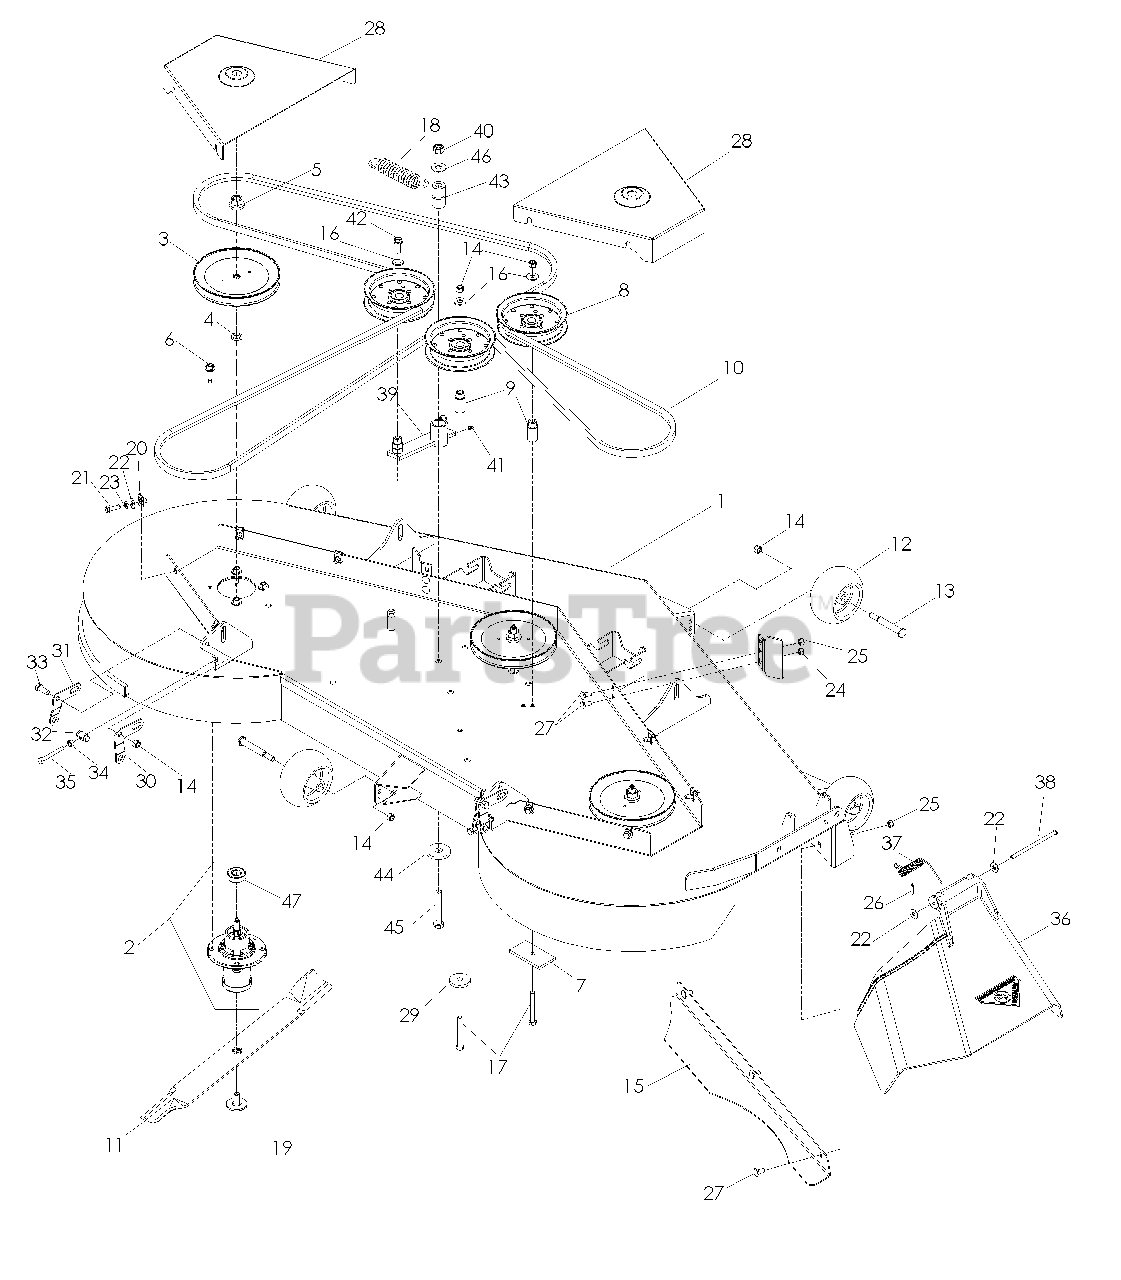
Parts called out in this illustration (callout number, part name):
1	DECK, W/DECALS
2	HOUSING ASSEMBLY
4	WASHER-SPACER
5	NUT 9/16 TOP CENTER LOCK
6	SCREW, WASHER HEAD
7	PAD, PAINTED
8	PULLEY, IDLER
9	IDLER BUSHING
10	BELT, DECK
11	BLADE, 25"
12	WHEEL, GAUGE
13	BOLT, SHOULDER
14	NUT 3/8-16 HEX NYLOC
15	CONFINEMENT PLATE, 72"
16	WASHER, 3/8 FLAT STD
17	HCS 3/8-16 x 3
19	BOLT, 7/16, BLADE
20	RETAINER, U TYPE
21	HCS 5/16-18 x 1
22	WASHER, 5/16 STD FLT
23	WASHER 5/16 SLW
25	NUT 5/16-18 HEX NYLOC
26	PIN, COTTER 1/8 x 3/4
27	RHSNB 5/16-18 x 3/4
28	SHIELD, BELT-72"
29	HEAVY WASHER
30	PITCH, ADJUST, RT
31	PITCH, ADJUST, LT
32	TRUNION, PITCH
33	HCS 3/8-16 x 1
34	NUT 5/16-18 HEX
35	HCS 5/16-18 x 2 1/2 TPBLT
36	DISCHARGE CHUTE-72"
37	SPRING-TORSION
38	PIN, CLEVIS 5/16
39	IDLER ARM WELDMT
40	NUT 1/2 HEX NYLOC
41	ZERK
42	HCS 3/8-16 x 1 WHIZLK
43	PIVOT BUSHING
44	SUPPORT WASHER
45	HCS 1/2-13 x 3 1/4
46	WASHER, 1/2 STD FLT
47	BALL BEARING
